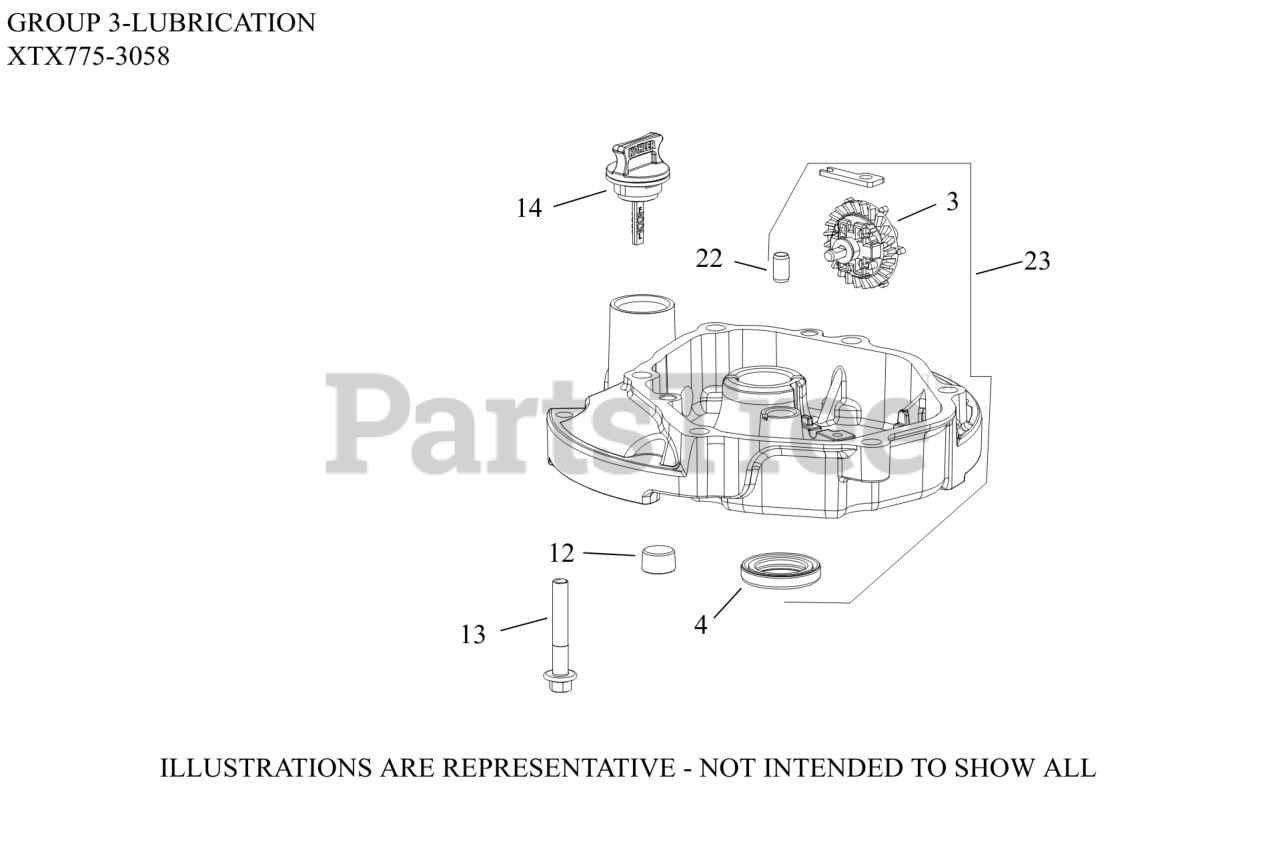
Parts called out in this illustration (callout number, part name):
3	GEAR ASSEMBLY, GOVERNOR
12	PLUG, PIPE (W/SEALANT)
13	SCREW, HEX FLANGE (M8)-USE 25 086 456-S
14	DIPSTICK ASSEMBLY
22	PIN, DOWEL (8mm)
23	KIT, OIL PAN
